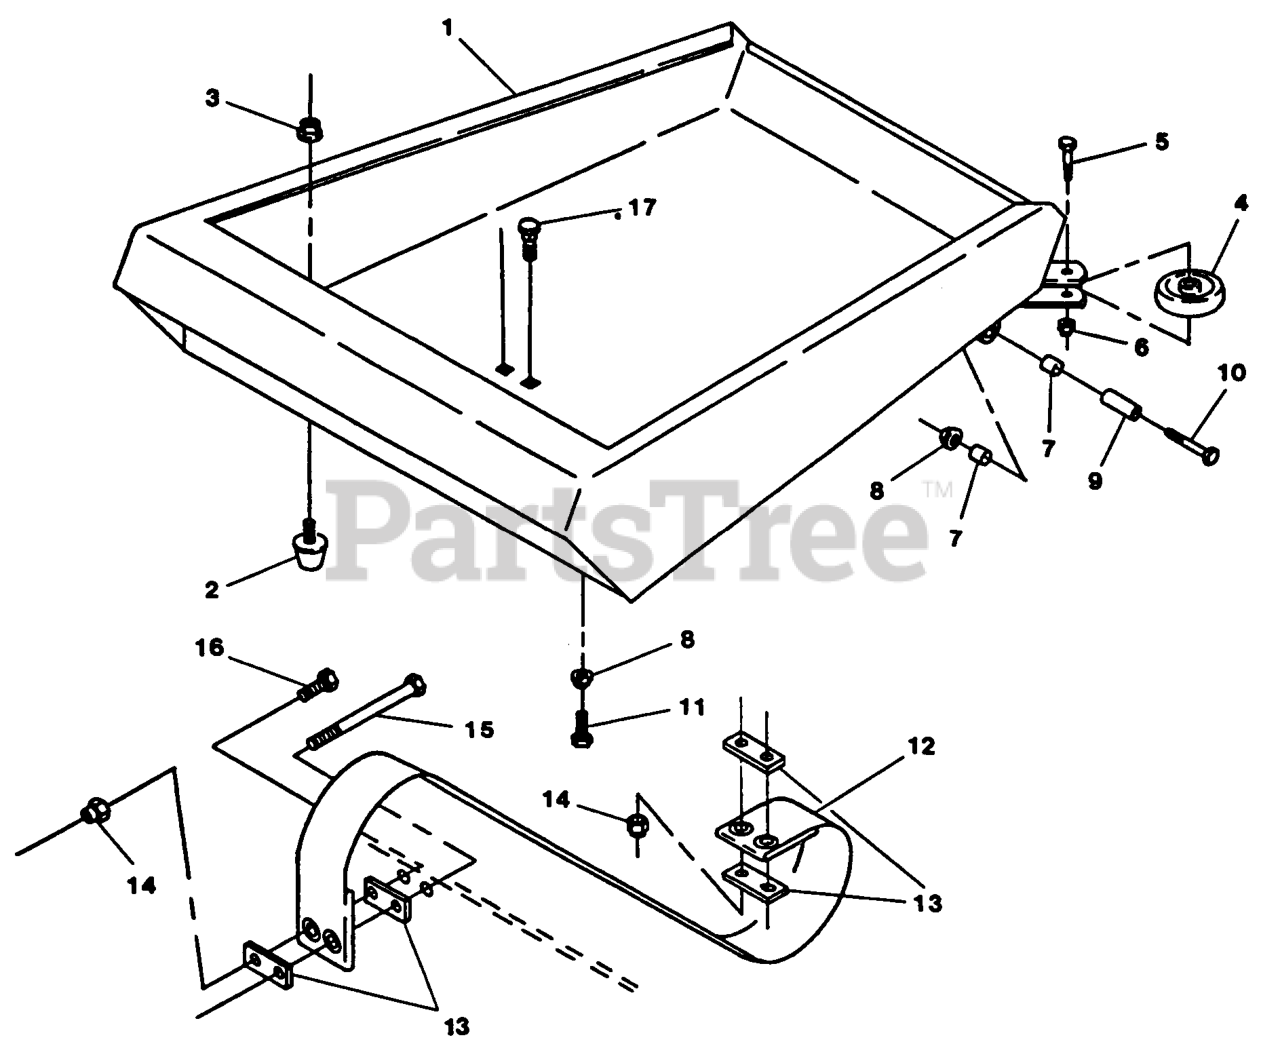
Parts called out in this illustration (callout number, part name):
2	BUMPER-RUBBER
4	WHEEL,RUBBER
7	SLEEVE-BEARING
9	BUSHING,BOX PIVOT
12	STRAP,BOX RESTRAINT
13	CLAMP,STRAP
17	Bolt, Carriage 1/4-20 X 1
